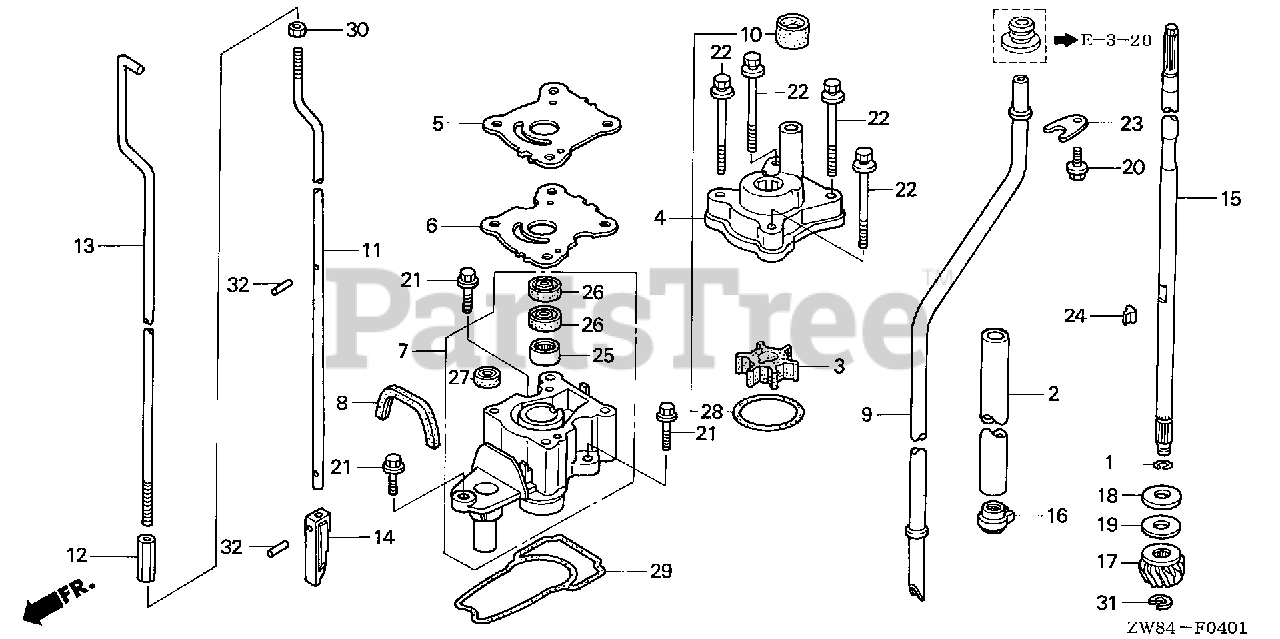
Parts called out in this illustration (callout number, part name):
1	CLIP, VALVE GUIDE
2	GUIDE, OIL (UL)
3	IMPELLER, PUMP (UL)
4	HOUSING ASSY., IMPELLER
5	COVER, IMPELLER
6	GASKET, IMPELLER
7	HOUSING, WATER PUMP (UL)
8	GROMMET, WATER PUMP HOUSING
9	TUBE, WATER (UL)
10	RING, WATER TUBE SEAL
11	ROD B, SHIFT (UL)
12	JOINT, SHIFT ROD
13	ROD A, SHIFT (L)
14	ROD, PUSH
15	SHAFT, VERTICAL (UL)
16	SLINGER, OIL (UL)
17	GEAR, PINION
18	WASHER A, THRUST BEARING
19	WASHER B, THRUST BEARING
19	WASHER C, THRUST BEARING
20	BOLT, FLANGE (6X12)
21	BOLT, FLANGE (6X20)
22	BOLT-WASHER (6X90)
23	PLATE, WATER TUBE SETTING
24	KEY, WOODRUFF
25	BEARING, NEEDLE (15X21X12)
26	SEAL, WATER (15X24X5)
27	SEAL, WATER (6MM)
28	O-RING (42.2X2.4)
29	O-RING, WATER PUMP HOUSING
30	NUT, HEX. (6MM)
31	E-RING (8MM)
32	ROLLER (2.5X11.8)
